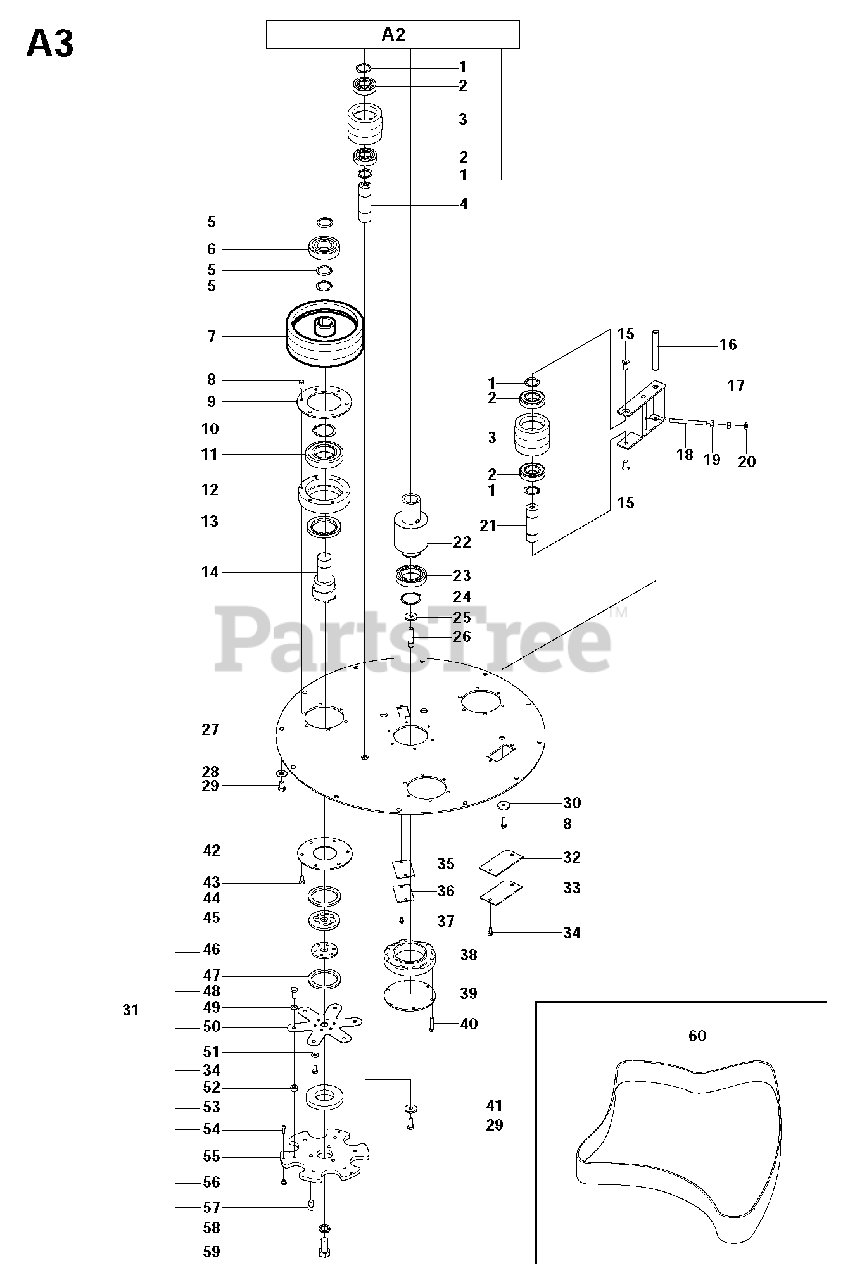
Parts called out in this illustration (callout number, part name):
20	WASHER
28	WASHER
34	SCREW EHHM
40	SCREW EHHM
49	WASHER
52	WASHER
